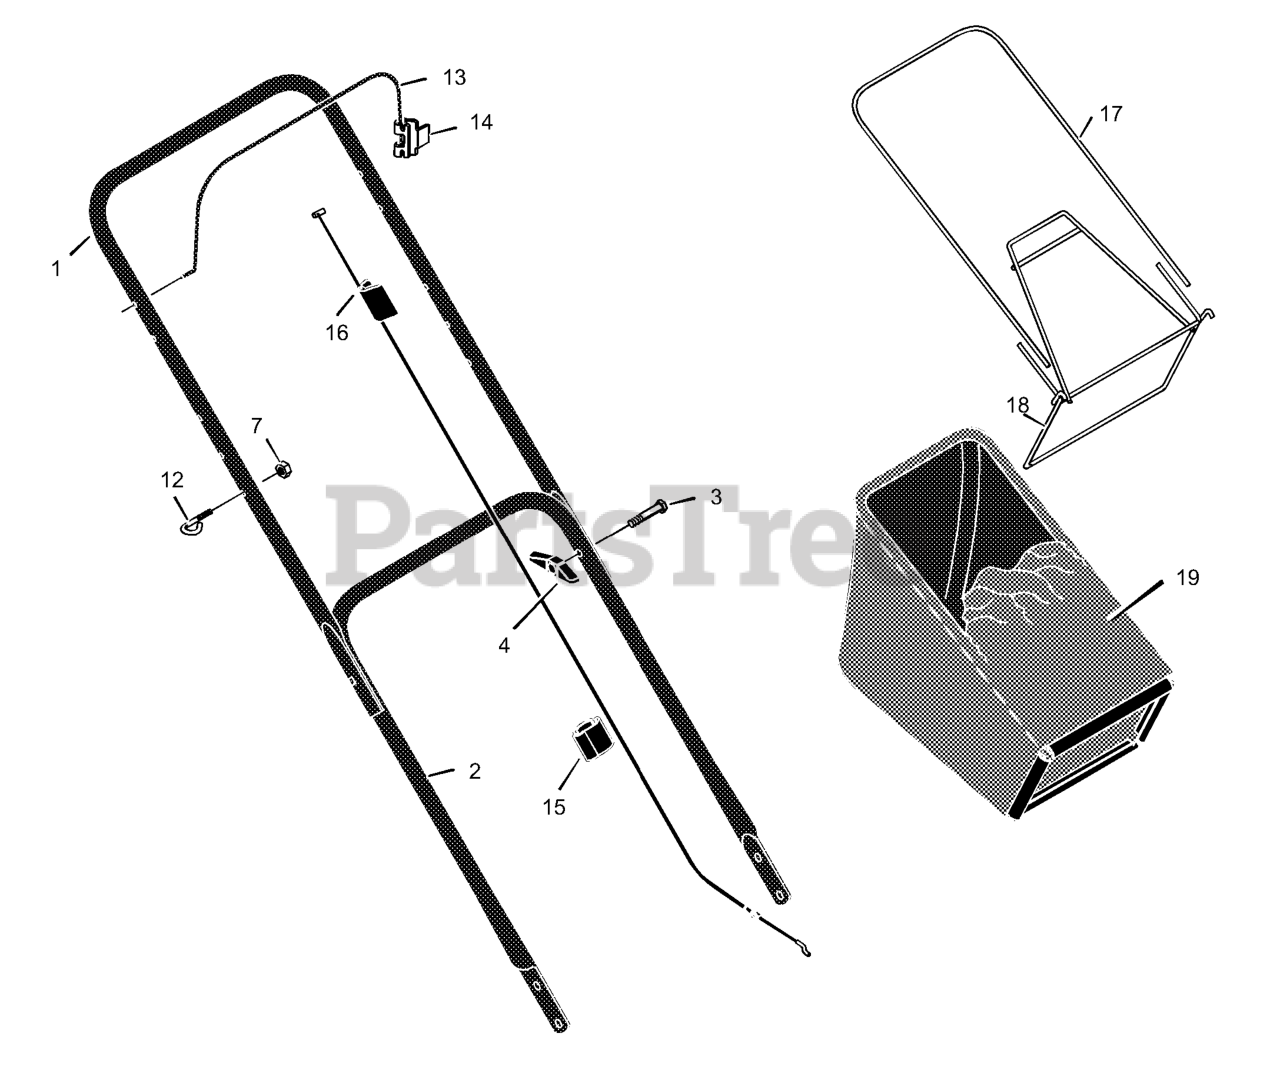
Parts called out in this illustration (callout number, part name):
1	Handle, Upper (Black)
2	Handle, Lower (Black)
4	Knob, Plastic
7	Locknut
12	Guide, Rope
13	Engine Stop Lever
14	Bracket, Stop Lever
15	Fastener, Double Cable
16	Engine Stop Cable
17	Frame, Top
18	Frame Assembly
19	Bag, Cloth - Black
